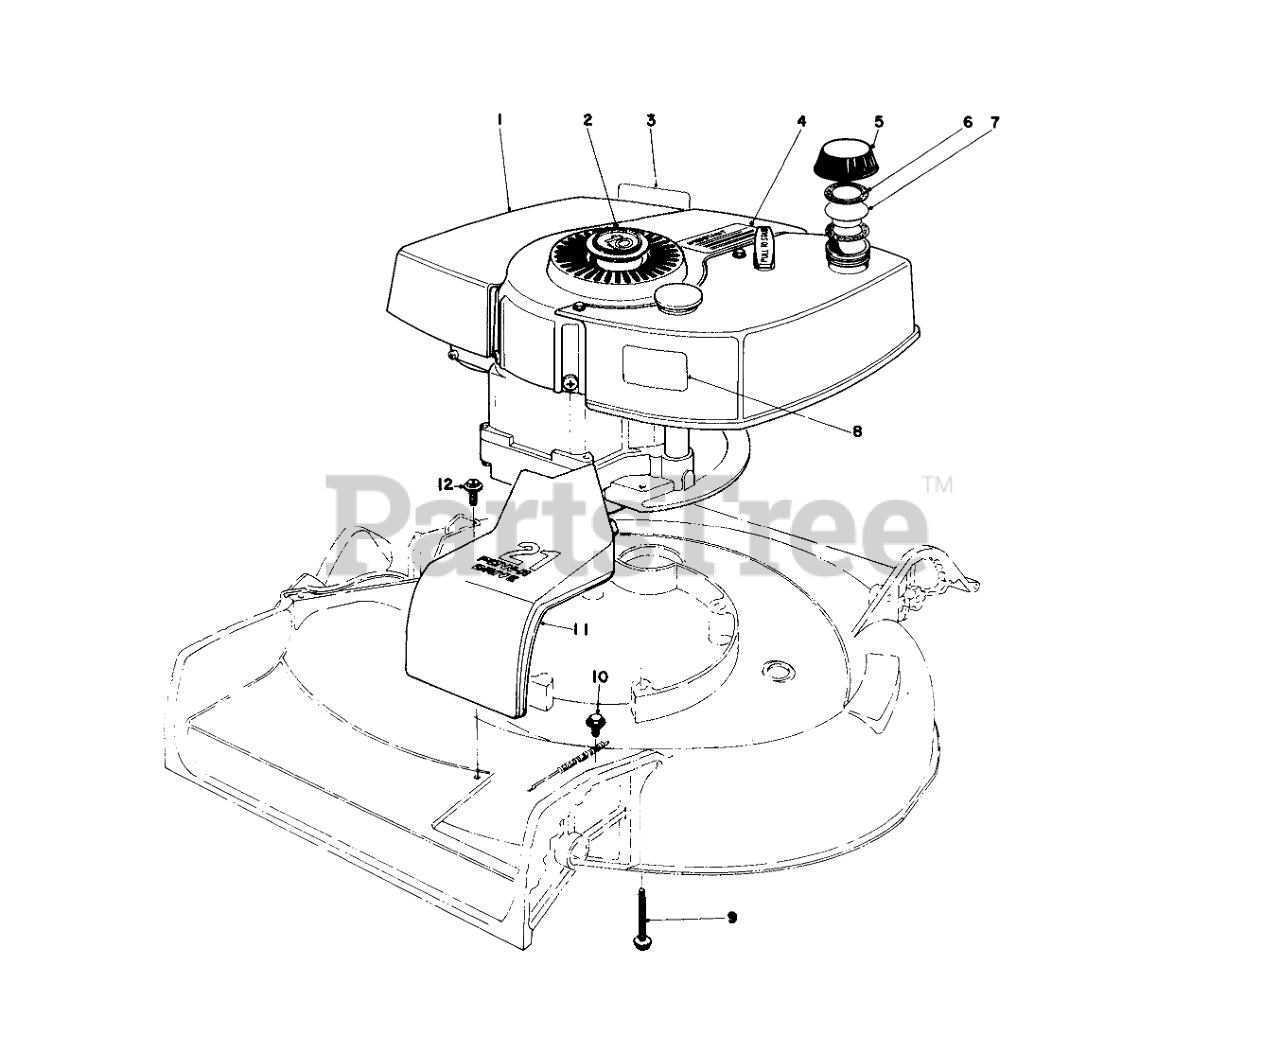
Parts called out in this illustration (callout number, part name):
1	Engine
2	PLUG BUTTON
3	Decal Maintenance
4	Decal Lockout
5	Gas Cap (Incl. Ref. #6 & 7)
6	GASKET
7	GAS CAP BAFFLE
8	Decal Engine
9	3/8-16 X 2-3/4 CAPSCR
10	SCREW-HWHTF
11	Cover Belt Drive
12	SCREW
